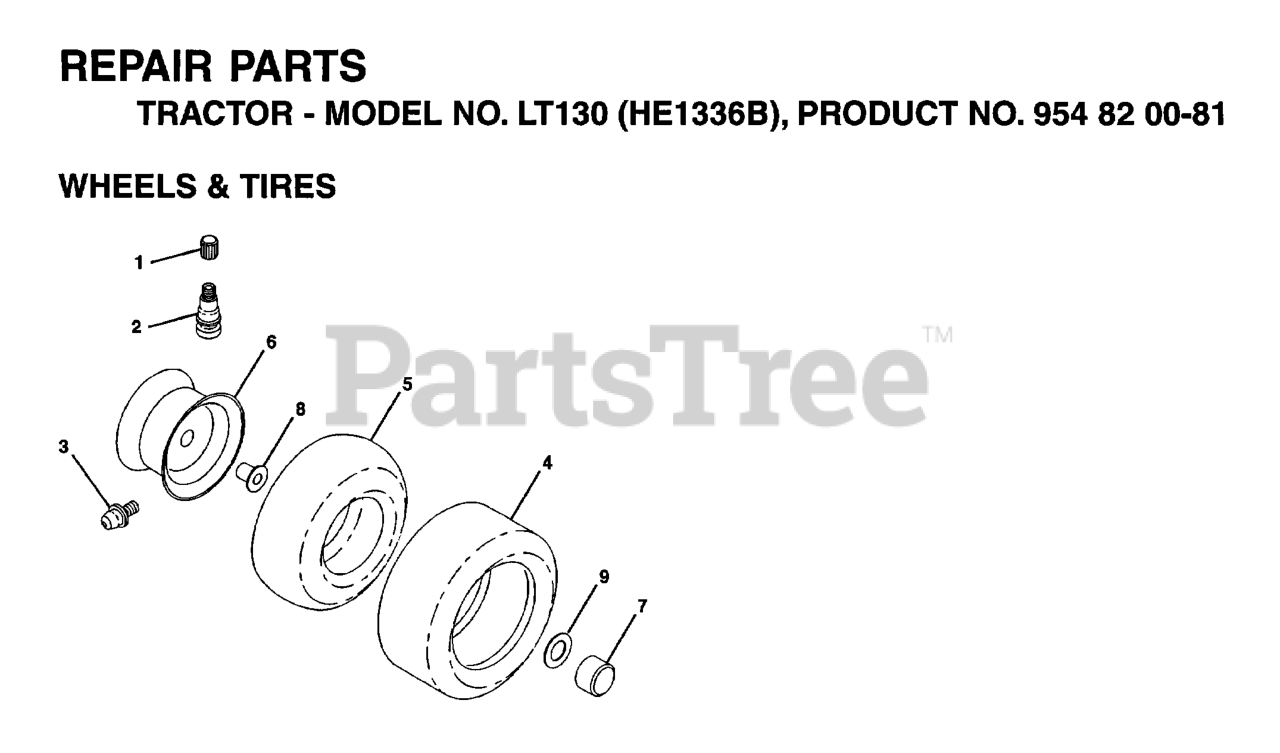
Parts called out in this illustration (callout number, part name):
2	VALVE STEM LT
3	FITTING LT
4	TIRE FRONT 15X6-6
5	TUBE.5.3/4.5/6
5	TUBE.16X6.5/7.5-8
6	RIM REAR 8"
6	RIM
7	CAP.HUB.FRONT.LT.BLACK
8	BEARING T
